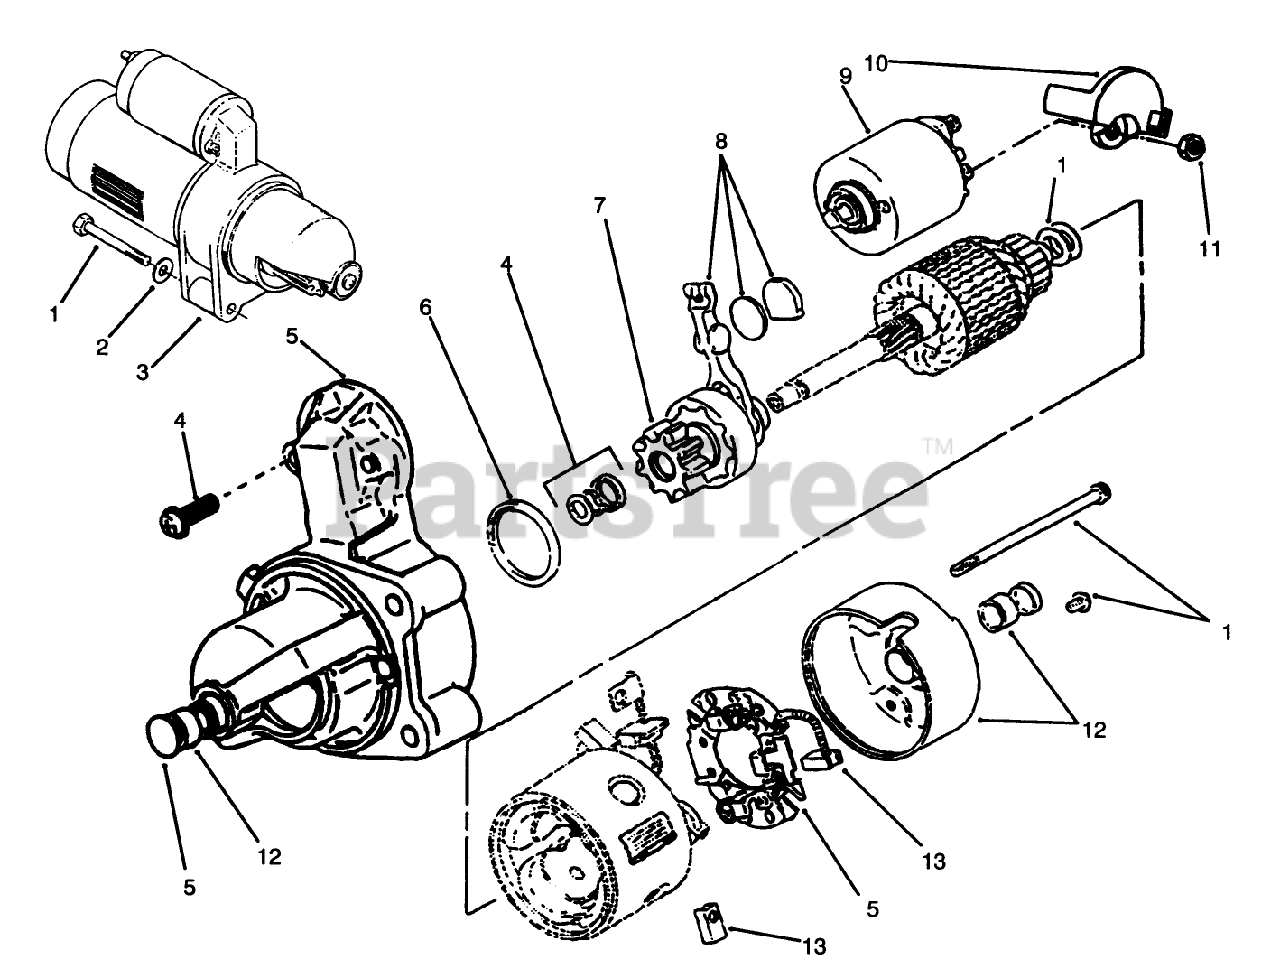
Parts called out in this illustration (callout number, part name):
2	WASHER
5	KIT-MTG BRKT
7	CLUTCH STARTER ASSEMBLY
9	STARTER SOLENOID KIT
11	WASHER-FLAT
